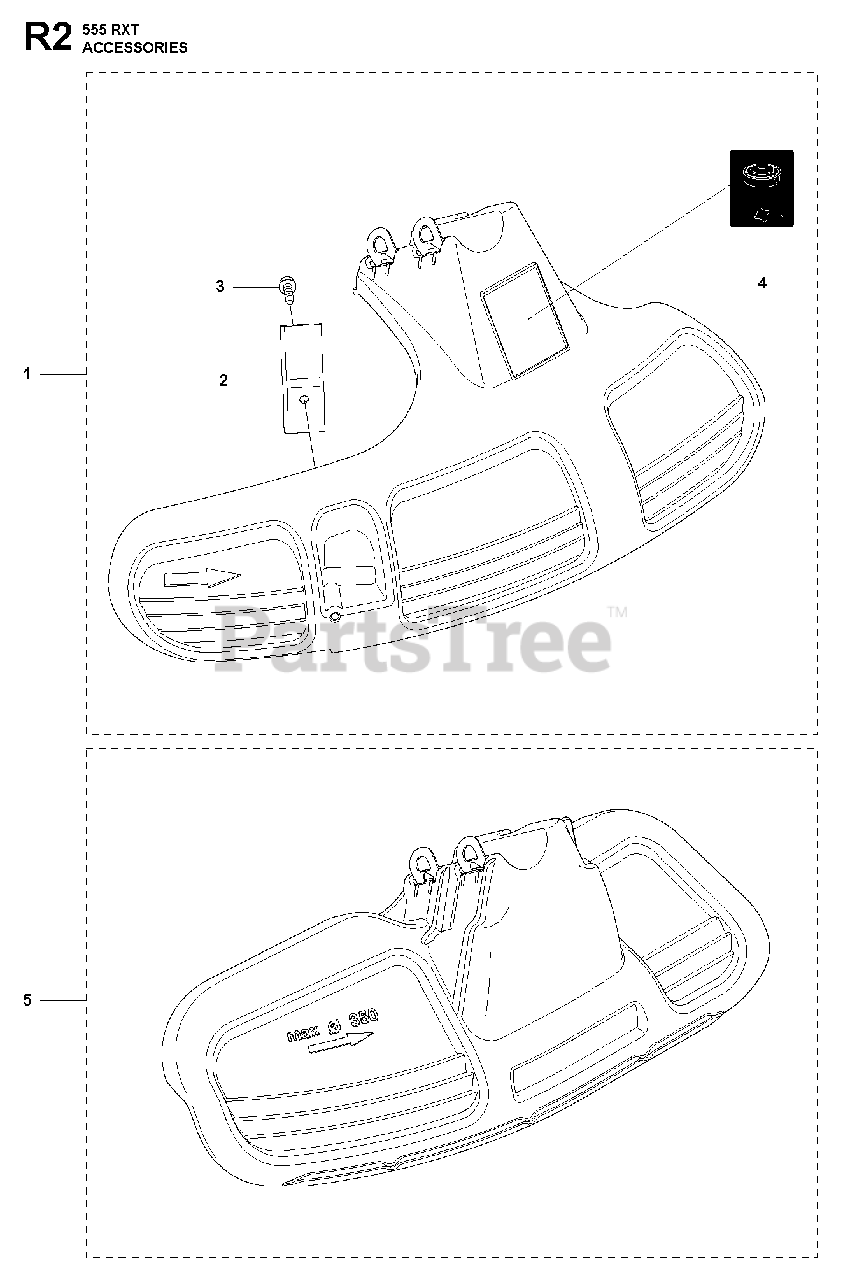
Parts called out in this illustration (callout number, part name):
1	PROTECTION
2	BLADE
3	SCREW
4	DECAL
5	BLADE GUARD GRASS
